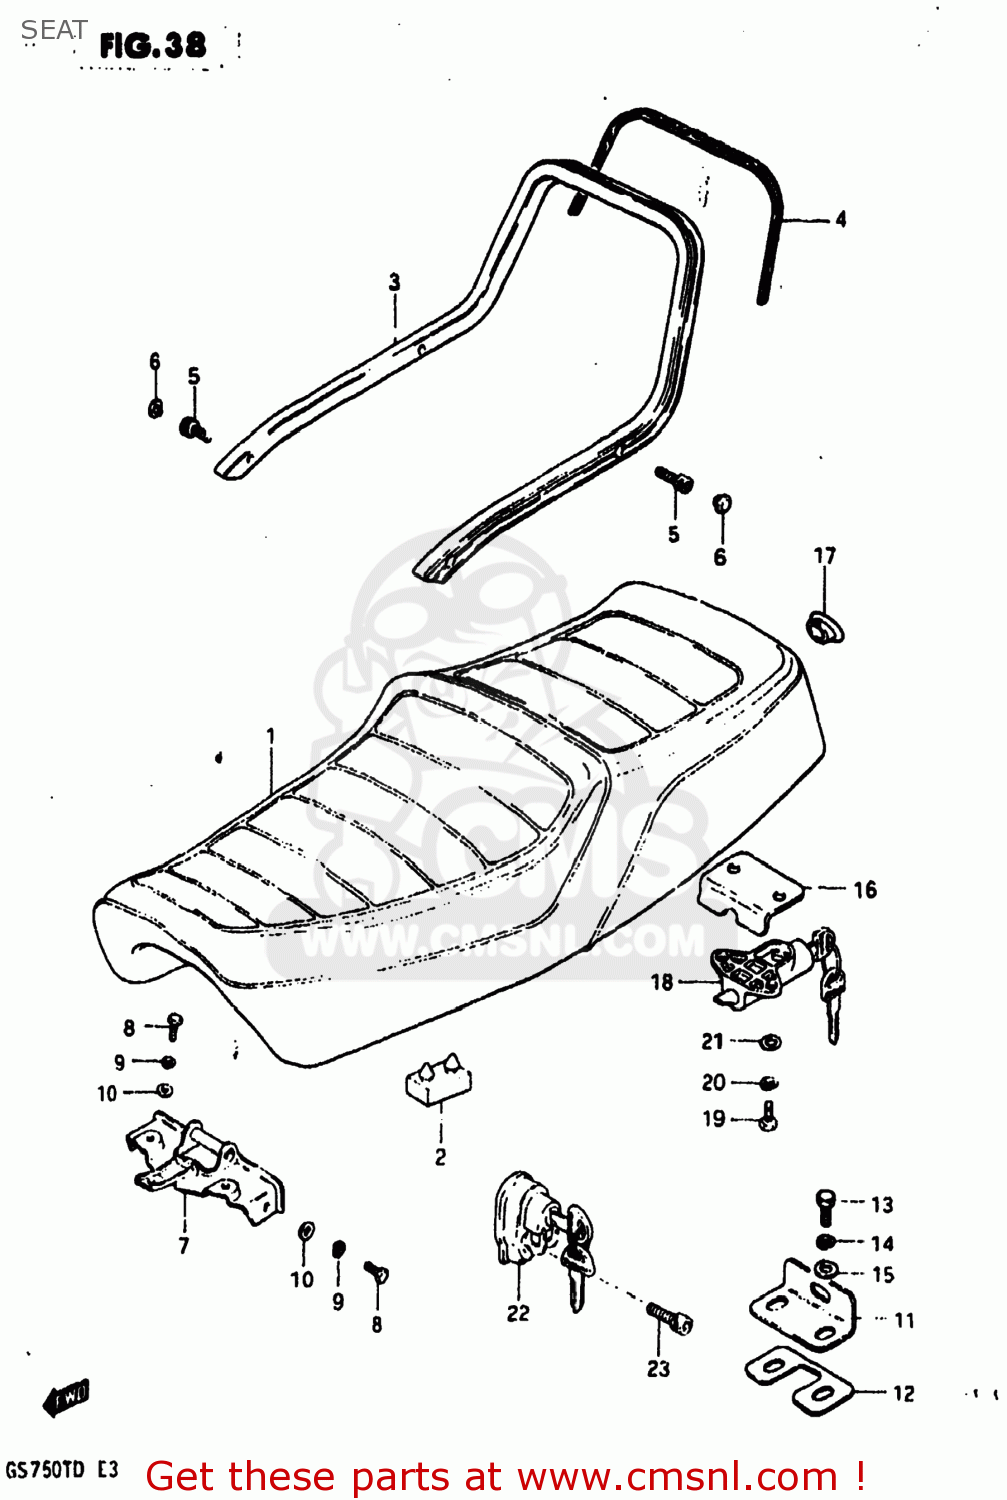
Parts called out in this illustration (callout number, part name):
1	SEAT ASSEMBLY
2	CUSHION
3	HANDLE,PILLION RIDER
4	RUBBER,PILLION RIDER HANDLE
5	BOLT
6	CAP(OD:14.5)
8	BOLT
9	LOCK WASHER
10	WASHER
11	STRIKER, SEAT LOCK
12	SHIM,SEAT LOCK STRIKER
13	BOLT, UPPER
14	LOCK WASHER
15	WASHER
16	GUIDE, PLATE
17	GROMMET
18	LOCK ASSEMBLY,SEAT
19	BOLT
20	LOCK WASHER
21	WASHER
22	LOCK ASSY,HELMET
23	BOLT 5X25
